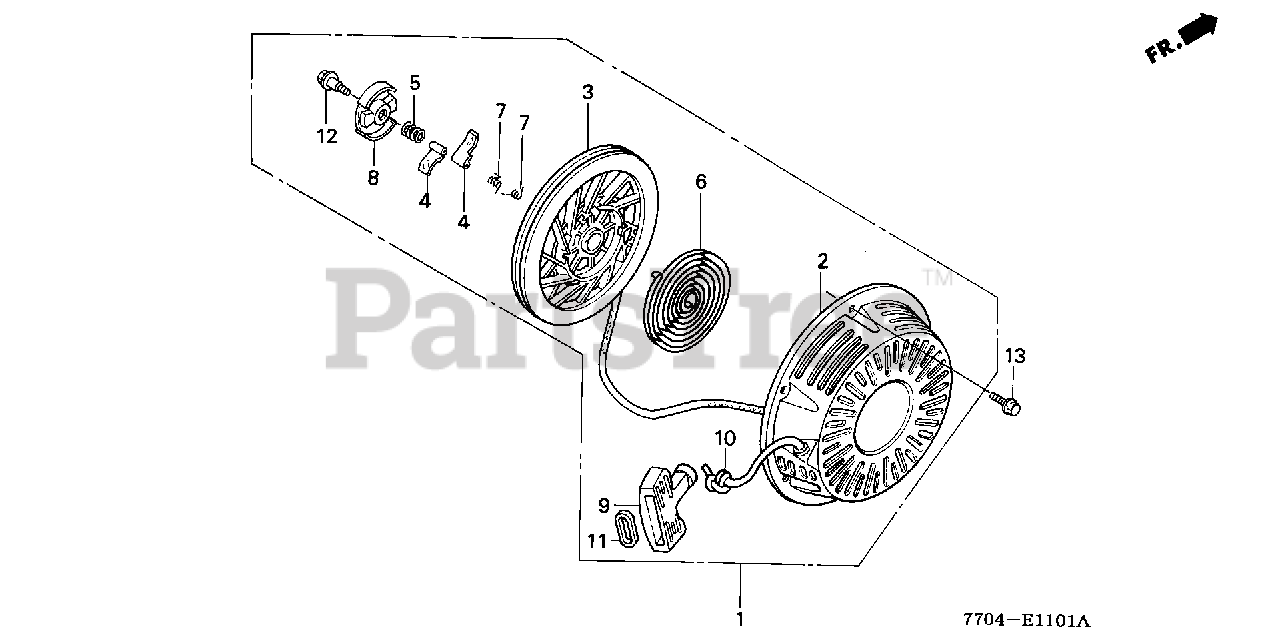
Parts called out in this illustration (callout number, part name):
1	STARTER ASSY., RECOIL *R280* (POWER RED)
2	CASE, RECOIL STARTER *R8* (BRIGHT RED)
2	CASE, RECOIL STARTER *R280* (POWER RED)
3	PULLEY, RECOIL STARTER
4	RATCHET, STARTER
5	SPRING, FRICTION
6	SPRING, STARTER RETURN
7	SPRING, RATCHET
8	RETAINER, SPRING
9	GRIP, STARTER
10	ROPE, RECOIL STARTER
11	REINFORCEMENT, GRIP
12	SCREW, CENTER
13	BOLT, FLANGE (6X8)
